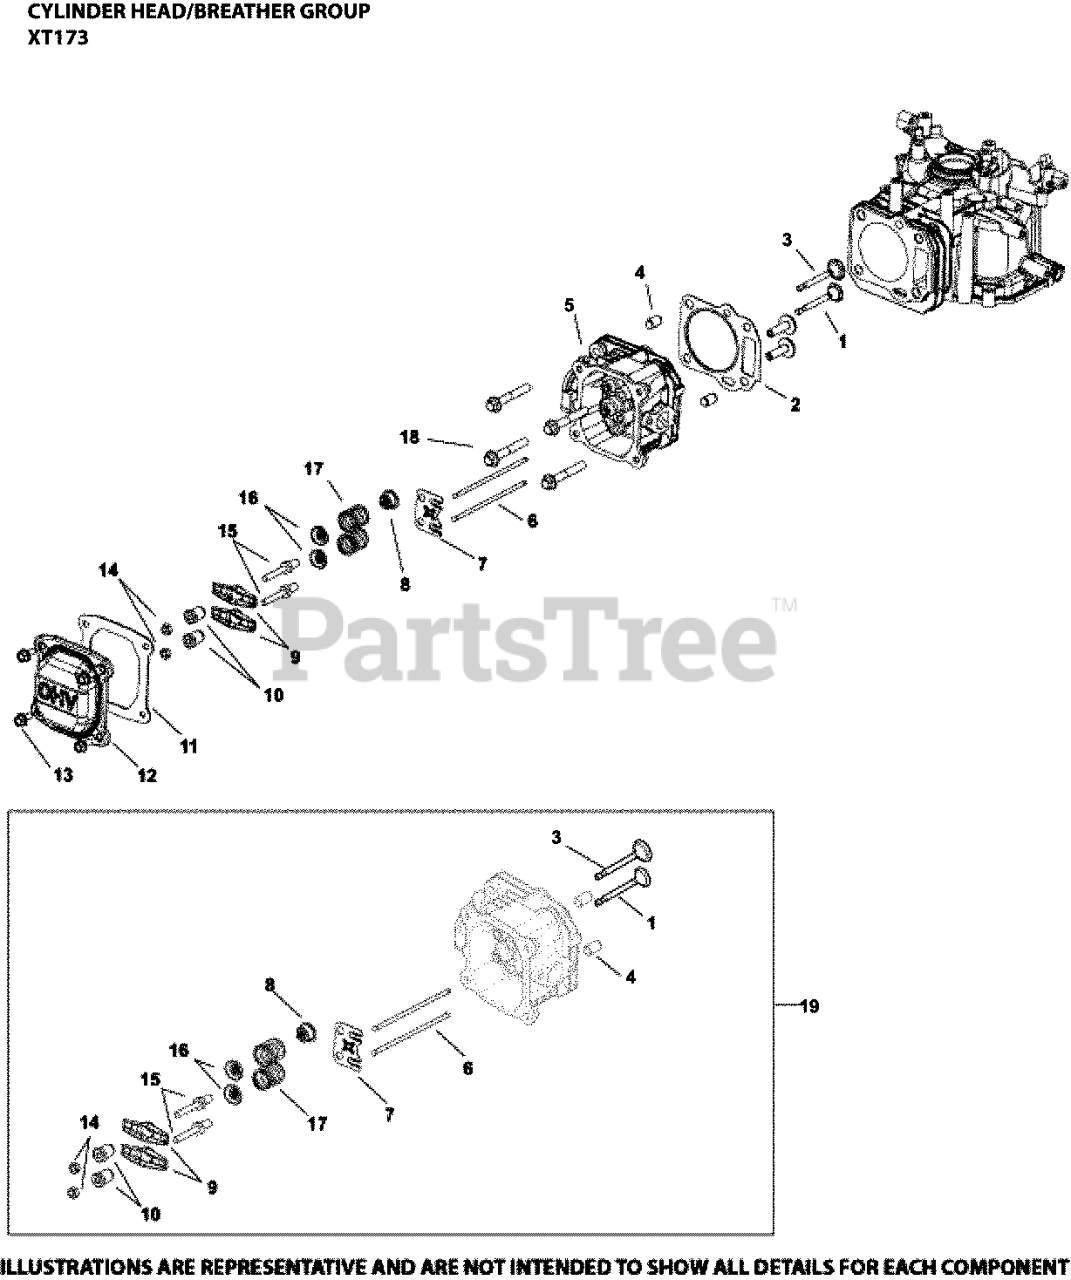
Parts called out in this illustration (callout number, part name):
1	VALVE, EXHAUST
2	KIT, HEAD GASKET USE 14 841 34-S
3	VALVE, INTAKE
4	DOWEL, CYLINDER HEAD-(#1438013S)
5	KIT, CYLINDER HEAD
6	ROD, PUSH
7	PLATE, PUSHROD GUIDE
8	SEAL, VALVE STEM
9	ARM, ROCKER
10	PIVOT, ROCKER ARM
11	GASKET, VALVE COVER
12	KIT, VALVE COVER - (#1409662S)
13	SCREW, HEX FLANGE (M6)-USE 25 086 433-S
14	NUT, HEX JAM
15	STUD, ROCKER ARM - (#1407222S)
16	RETAINER, VALVE SPRING
17	SPRING, VALVE
18	SCREW, HEX FLANGE M8
19	KIT, VALVE TRAIN
